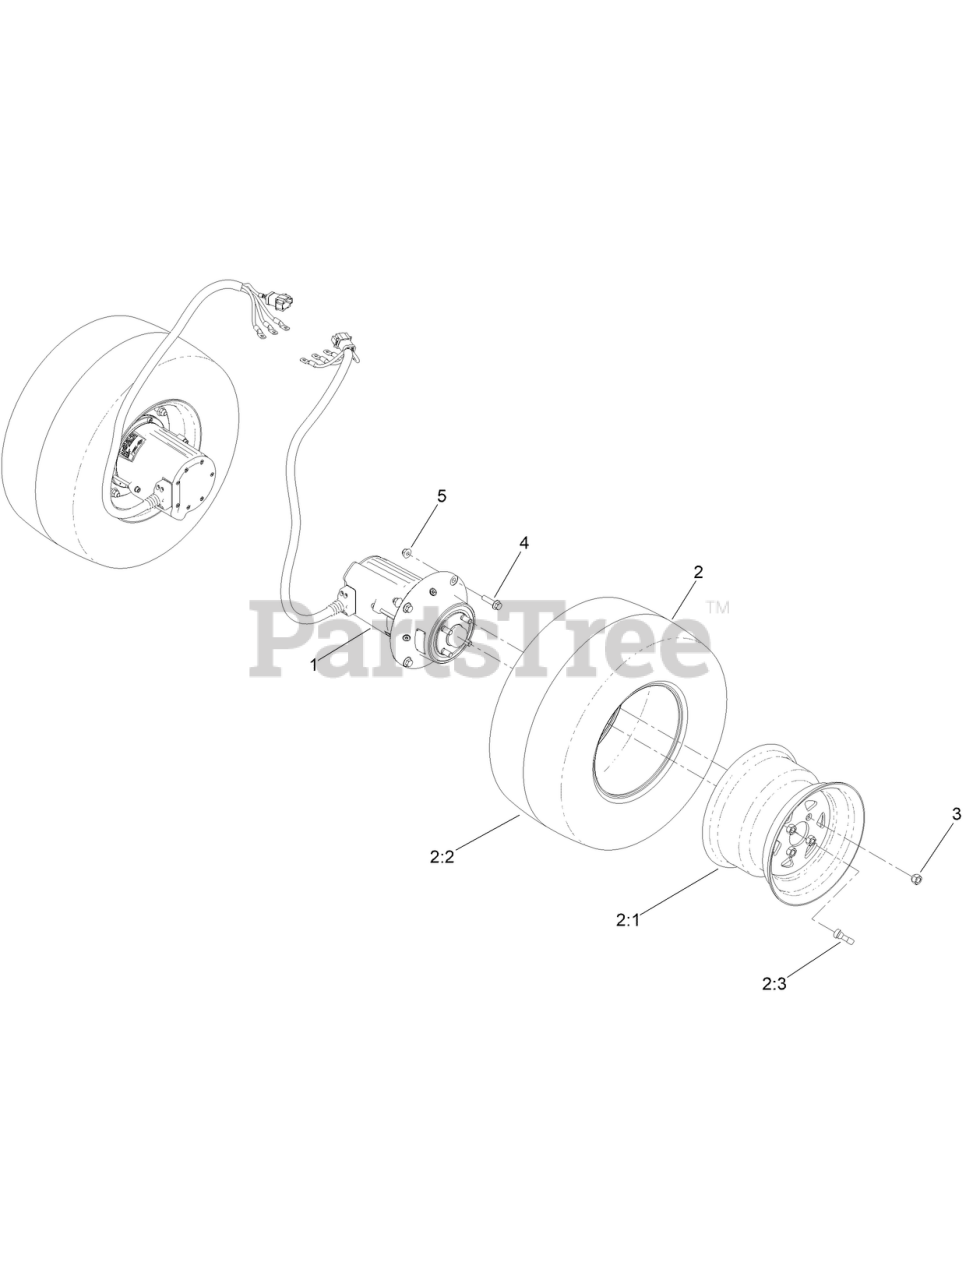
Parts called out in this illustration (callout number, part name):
1	MOTOR/GEARBOX ASM-48V,
2	WHEEL AND TIRE ASM
2:1	RIM-10 IN
3	NUT-WHEEL
4	SCREW-HHF
5	NUT-HF, NI
